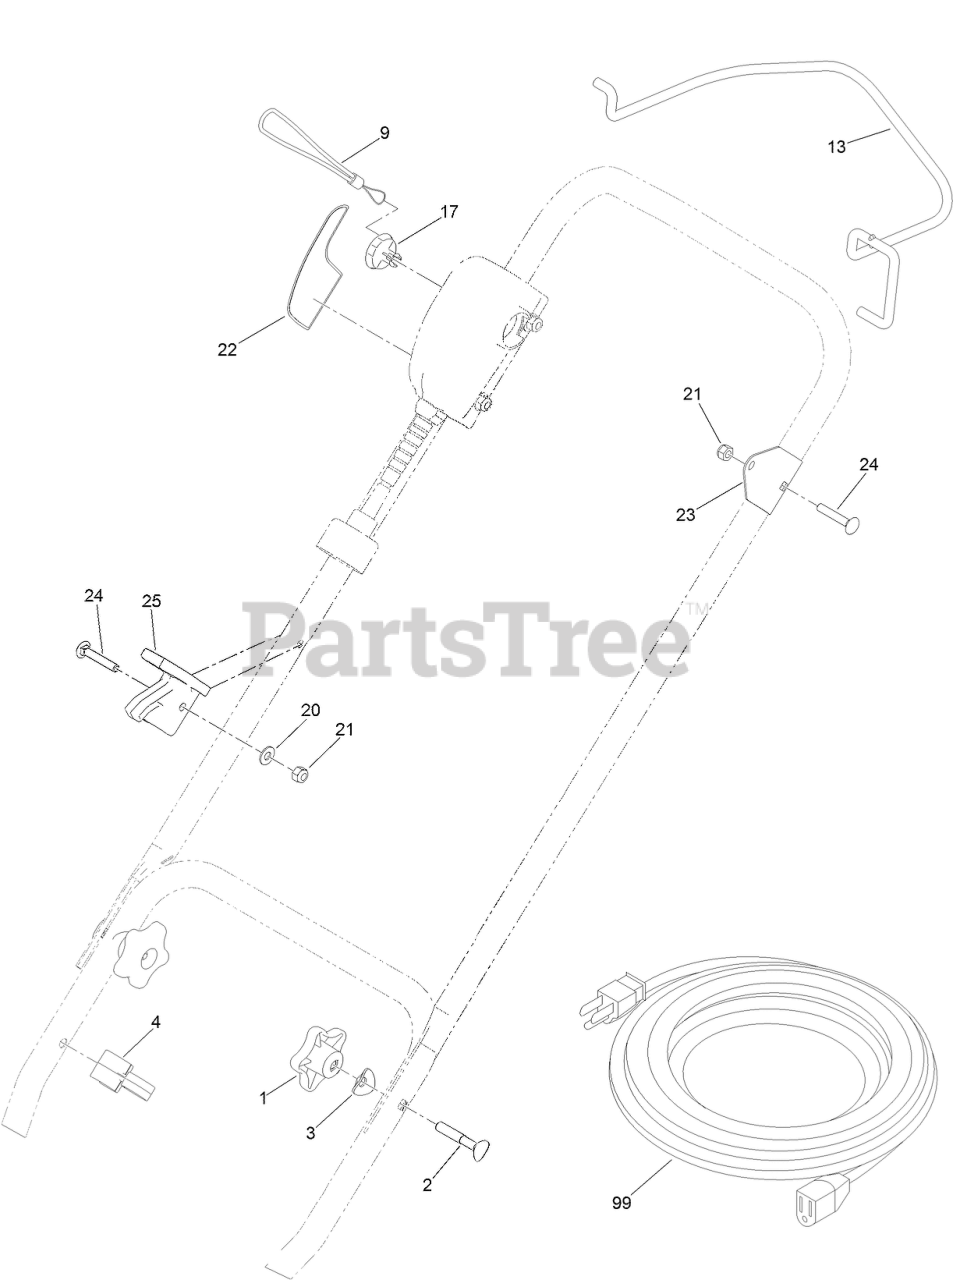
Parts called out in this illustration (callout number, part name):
1	KNOB-HANDLE
2	SCREW-HANDLE
3	WASHER
4	GUIDE-CABLE
9	CORD-KEY
17	KEY-BAIL
20	WASHER-FLAT
21	NUT-LOCK, NI
22	DECAL-OPERATION
23	BRACKET-BAIL
24	SCREW-CARR
25	LOCK-CORD
99	CORD-EXTENSION, COLD WEATHER
